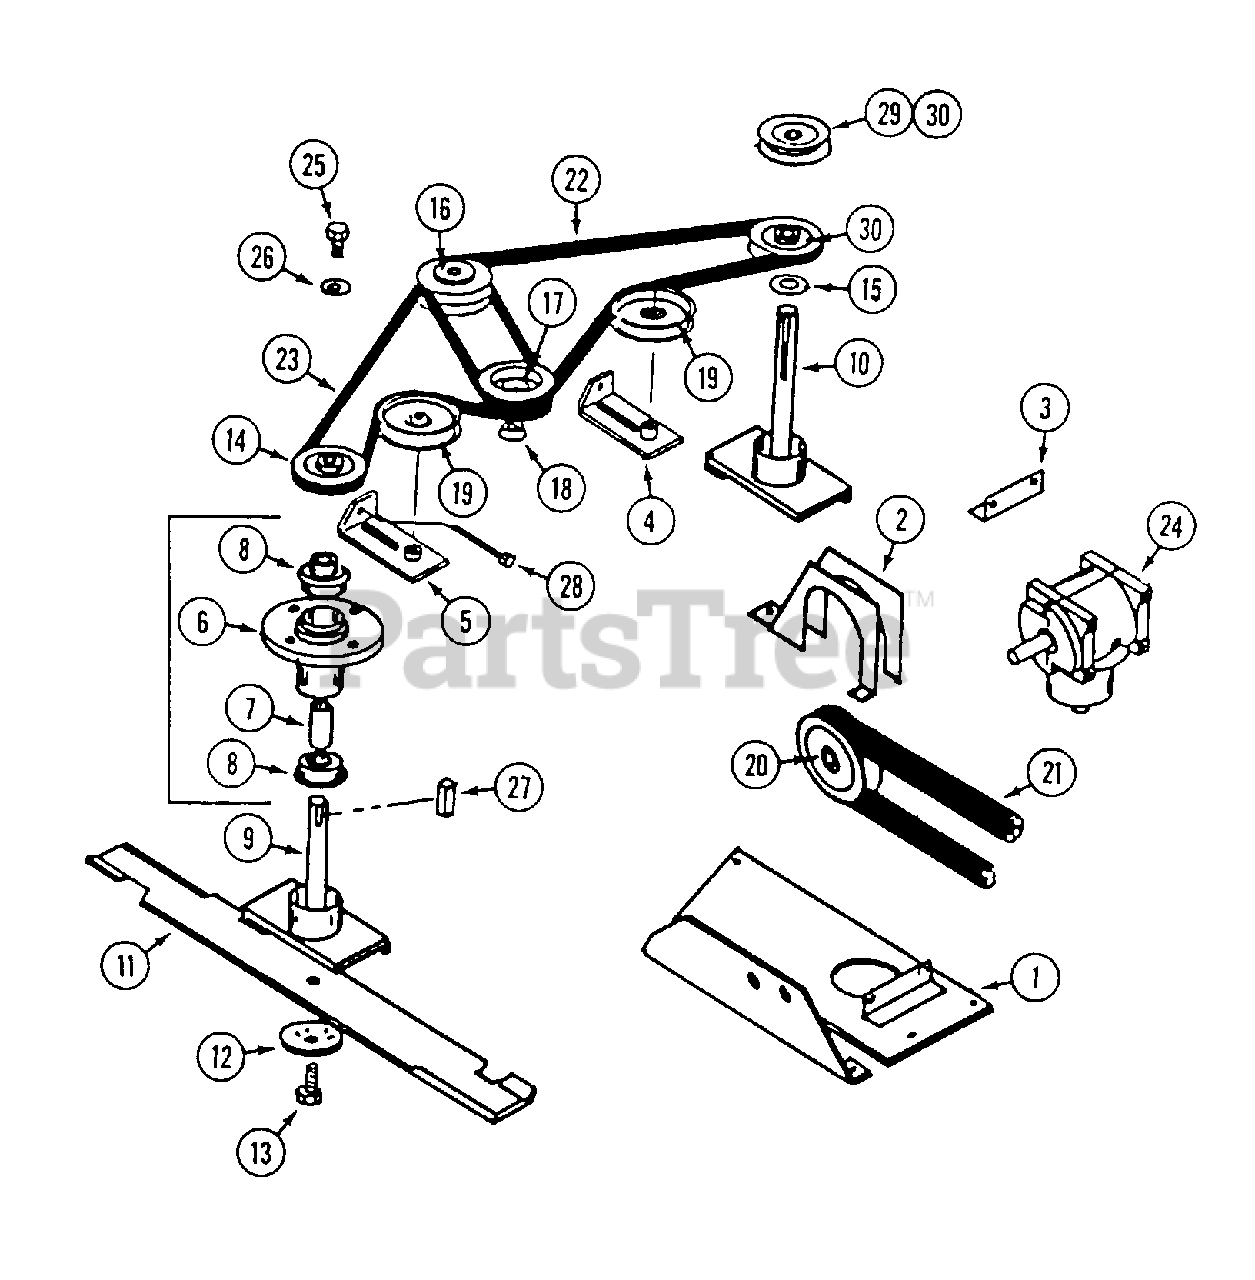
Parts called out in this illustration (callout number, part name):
1	MOUNT - gear box
3	ANGLE - gear box mount
4	TIGHTENER - belt
5	TIGHTENER - belt
6	HOUSING - spindle
7	SPACER - spindle
8	BEARING - spindle
9	SHAFT - spindle
10	SHAFT - spindle
12	WASHER - blade
13	BOLT - 3/8" - 24 x 1-1/4"
14	PULLEY - spindle
15	WASHER - spacer
16	PULLEY - spindle, double
17	PULLEY - gear box output
18	HUB - pulley
19	PULLEY - idler
20	PULLEY - gear box input
22	BELT - deck
24	GEAR BOX
25	BOLT - 5/16" - 24 x 3/4"
26	WASHER - 5/16", 10 ga.
27	KEY - 3/16" x 3/16" x 1"
28	BOLT - 3/4" - 20 x 4"
29	PULLEY - spindle
